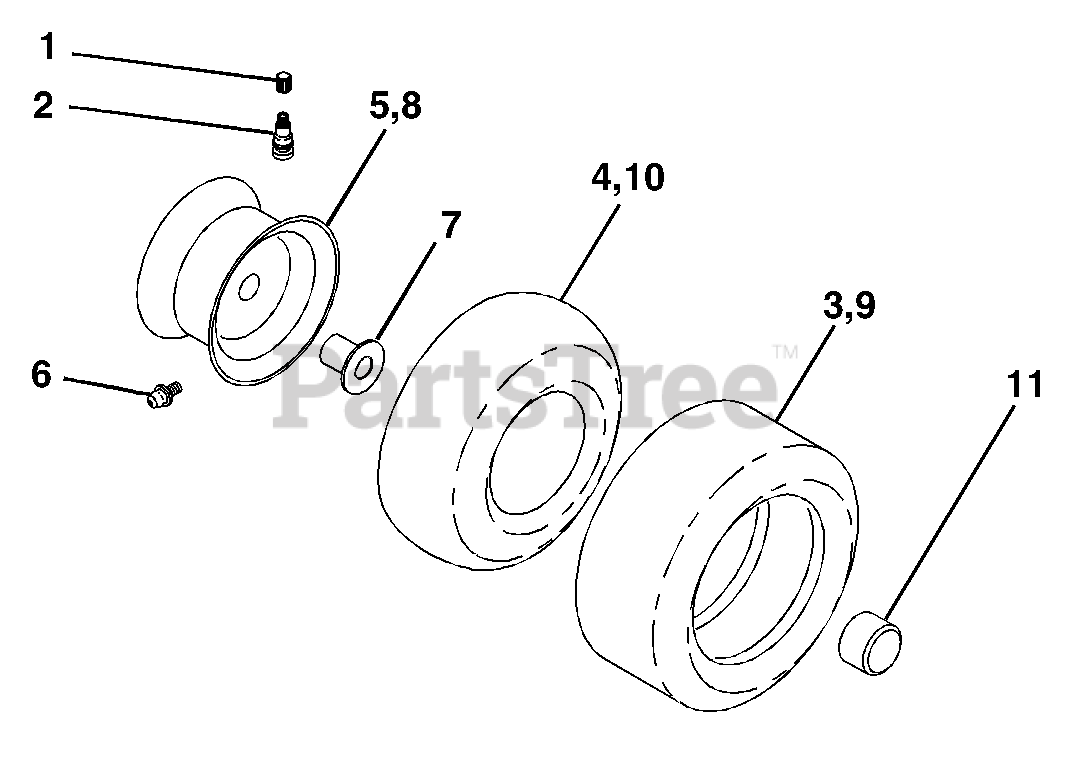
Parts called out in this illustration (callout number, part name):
1	Cap Valve Tire
2	Stem Valve
3	Tire F Ts 15 x 6 0 - 6 Service
4	Tube Front (Service Item Only)
5	Rim Asm 6" front Silver Service
6	Fitting Grease (Front Wheel Only)
7	Bearing Flange (Front Wheel Only)
8	Rim Asm 8" rear Silver Service
9	Tire R Ts 18 x 9 5-8 C Service
10	Tube Rear (Service Item Only)
11	Cap Axle Blk 1 50 x 1 00
